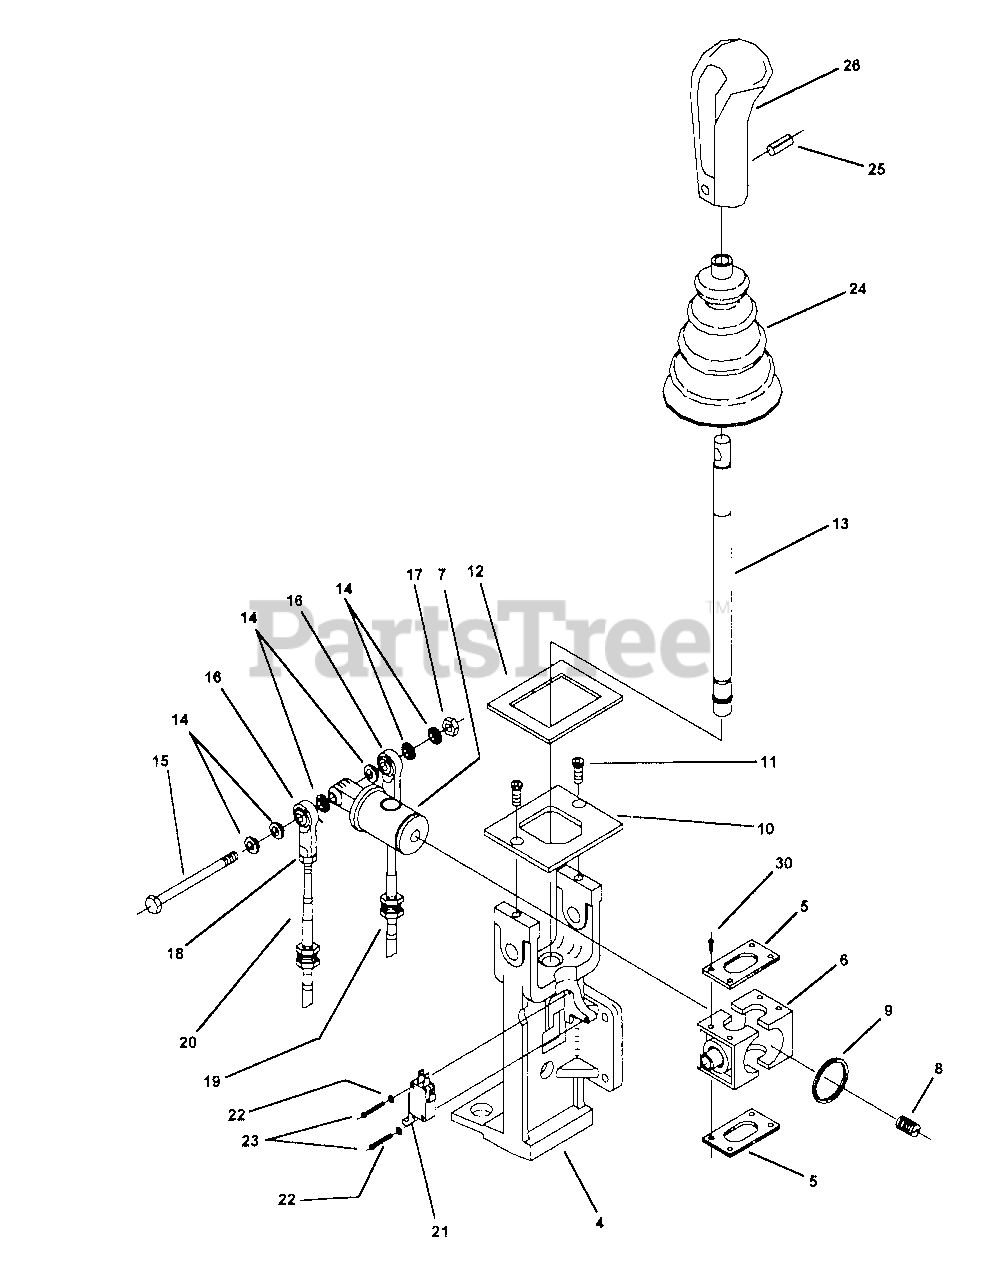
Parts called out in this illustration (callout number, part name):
5	PIVOT BLOCK PLATE, JOYSTICK
6	PIVOT BLOCK, Delrin Plastic
7	PIVOT SHAFT, Delrin Plastic
8	BALL PLUNGER, 3/8-16 X 5/8"
9	SNAP RING, SPIRLOCK
10	TOP PLATE, JOYSTICK
11	SCREW, 1/4-20 X 1/2", FLATHEAD
12	GASKET, FOAM
13	JOYSTICK SHAFT ASSEMBLY
15	CAP SCREW, 1/4-20 X 3", HEX HEAD
16	BALL JOINT, 1/4-28, FEMALE
17	NUT, 1/4-20, STOVER
18	NUT, 1/4-28, (comes with 19 & 20)
19	PUSH-PULL CABLE, 58"
20	PUSH-PULL CABLE, 42"
21	SWITCH, SPDT, MINIATURE
22	LOCK WASHER, #4 STAR
23	SCREW, #4-40 X 3/4"
24	BELLOWS BOOT
25	PIN, SPIRAL ROLL, 3/16 X 1" LIGHT DUTY
26	HANDLE GRIP
30	SCREW, #6-32 X 3/8", TYPE B POINT, SLOTTED HD.
